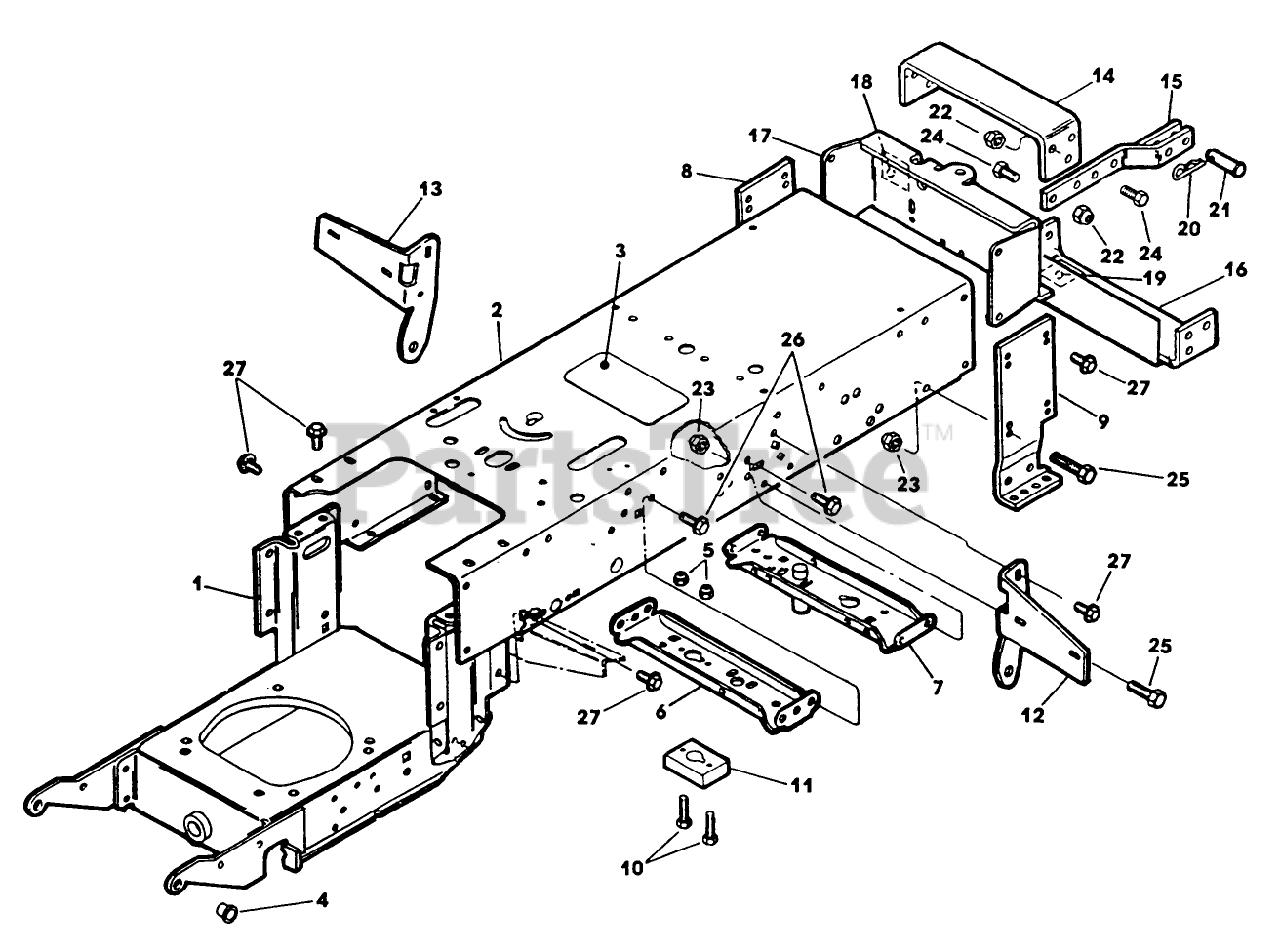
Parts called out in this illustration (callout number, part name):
4	BEARING-NYLINER
5	NUT-LOCK, CONE
6	SUPPORT *B
10	SCREW
11	BRACKET-SUPPORT *B
13	SUPPORT - RH
20	PIN - SPRING CLIP
22	NUT-LOCKING
23	NUT
25	SCREW
